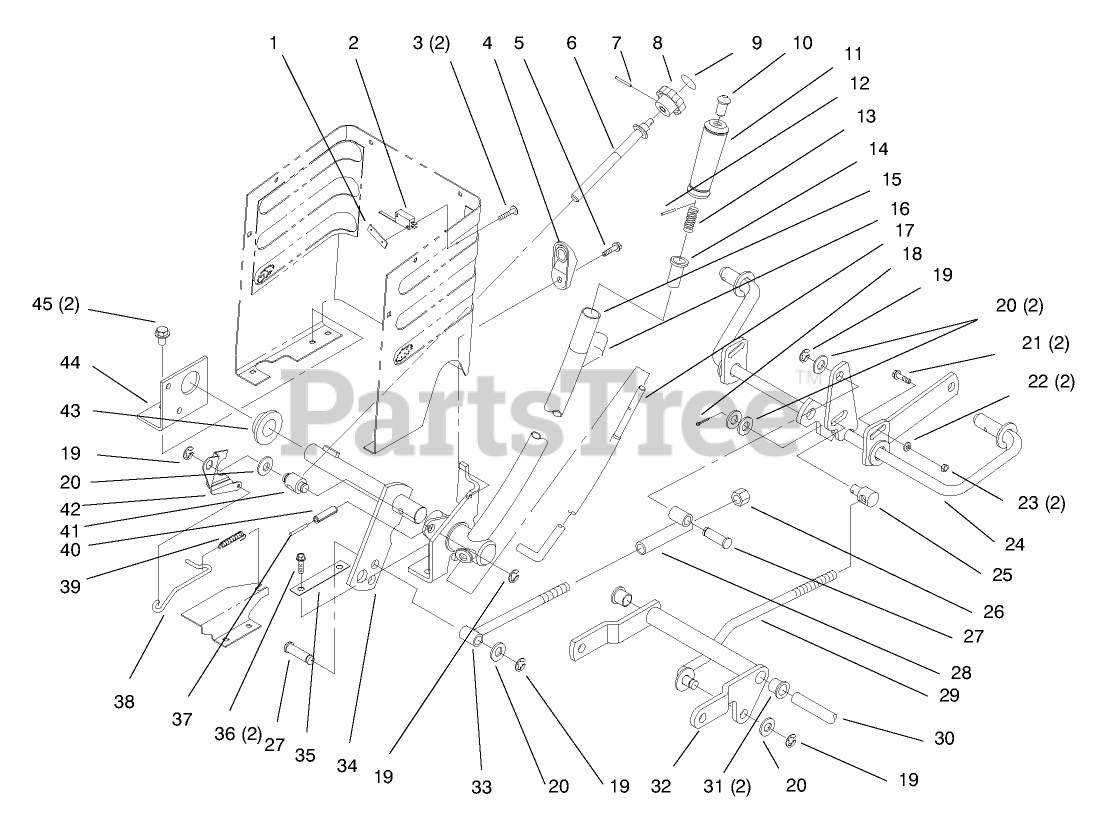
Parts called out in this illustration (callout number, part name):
1	NUT-SPEED
2	SWITCH-MICRO
3	SCREW-PPHTF
4	WEDGE - HOC
5	SCREW-HWH
7	PIN-SPIROL
18	PIN-COTTER
19	RING-RETAINING, EXTERNAL
20	WASHER-FLAT
21	BOLT-CARR
22	WASHER-FLAT
23	NUT-LOCK, NI
24	SHAFT-GAGE
26	NUT-LOCK, NI
31	BUSHING-FLANGE
32	ARM-PIVOT
34	SHAFT-LIFT
36	SCREW-HWHTF
37	PIN-SPRING
38	ROD - HOC INDICATOR
39	SPRING - EXTENSION
40	PIN-ROLL
42	PLATE - HOC GAGE
43	BEARING-FLANGE
44	BRACKET-PIVOT, LINKAGE
45	SCREW-HWHTF
